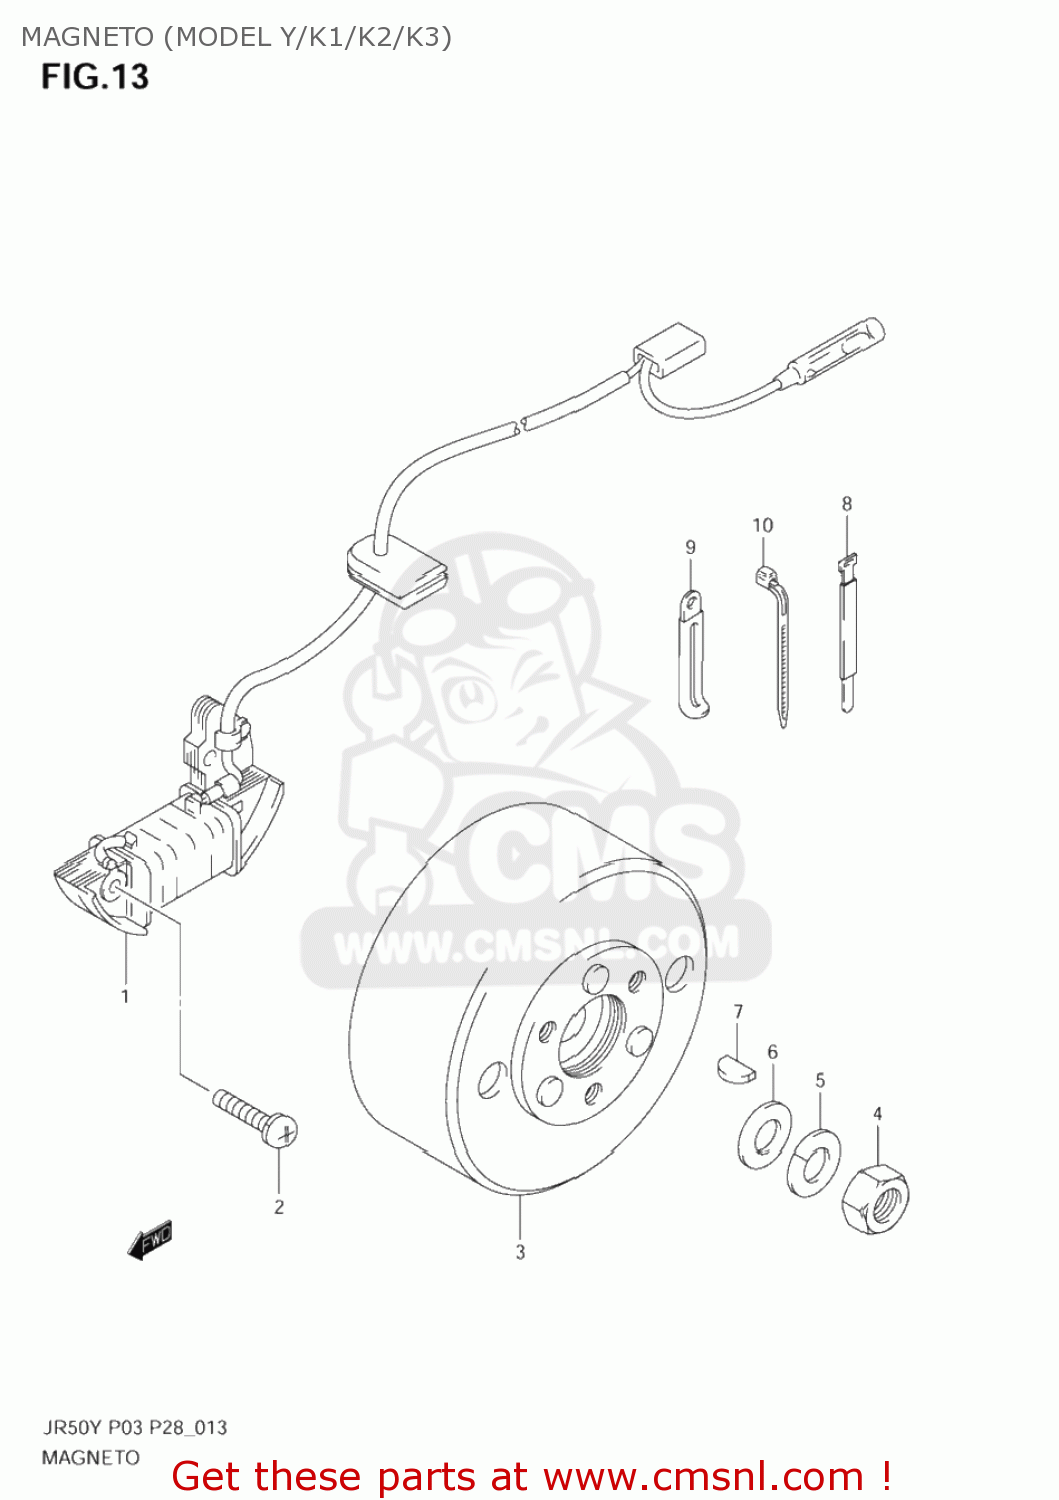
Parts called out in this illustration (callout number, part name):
1	COIL ASSY,IGNITION PRIMARY
2	SCREW
3	ROTOR ASSY
4	NUT
5	WASHER
6	WASHER
7	KEY
8	CLAMP
9	CLAMP(L:65)
10	CLAMP(L:165)
